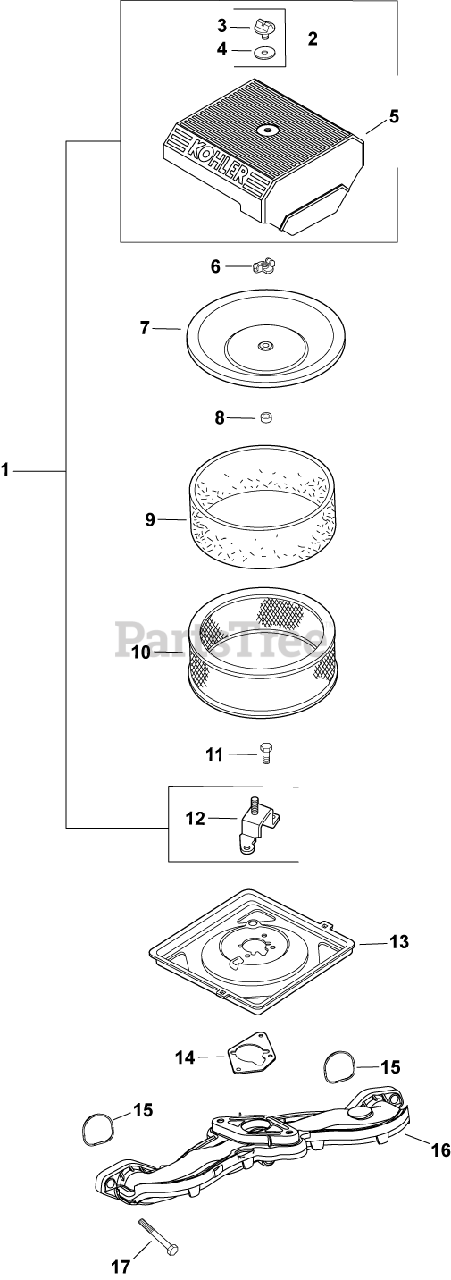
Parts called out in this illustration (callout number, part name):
1	KIT, AIR CLEANER COVER
2	KIT, KNOB W/SEAL
3	KNOB, COVER
5	COVER, AIR CLEANER
6	NUT, WING
7	COVER, INNER AIR CLEANER
8	SEAL, INNER AIR CLEANER
9	ELEMENT, PRECLEANER (LOW)
10	ELEMENT, AIR CLEANER - Also available Retail Packaged 47 883 03-S1 Air Filter Kit
11	SCREW, FLG THD FRM M6X1.0X16
12	BRACKET,AIR CLEANERBASE-USE 24 126 206-S
13	BASE, AIR CLEANER-USE 24 094 84-S
14	GASKET, AIR CLEANER BASE
15	GASKET, INTAKE MANIFOLD USE 24 041 79-S
16	MANIFOLD, METAL INTAKE
17	SCREW, FLG M6X1.0X55
